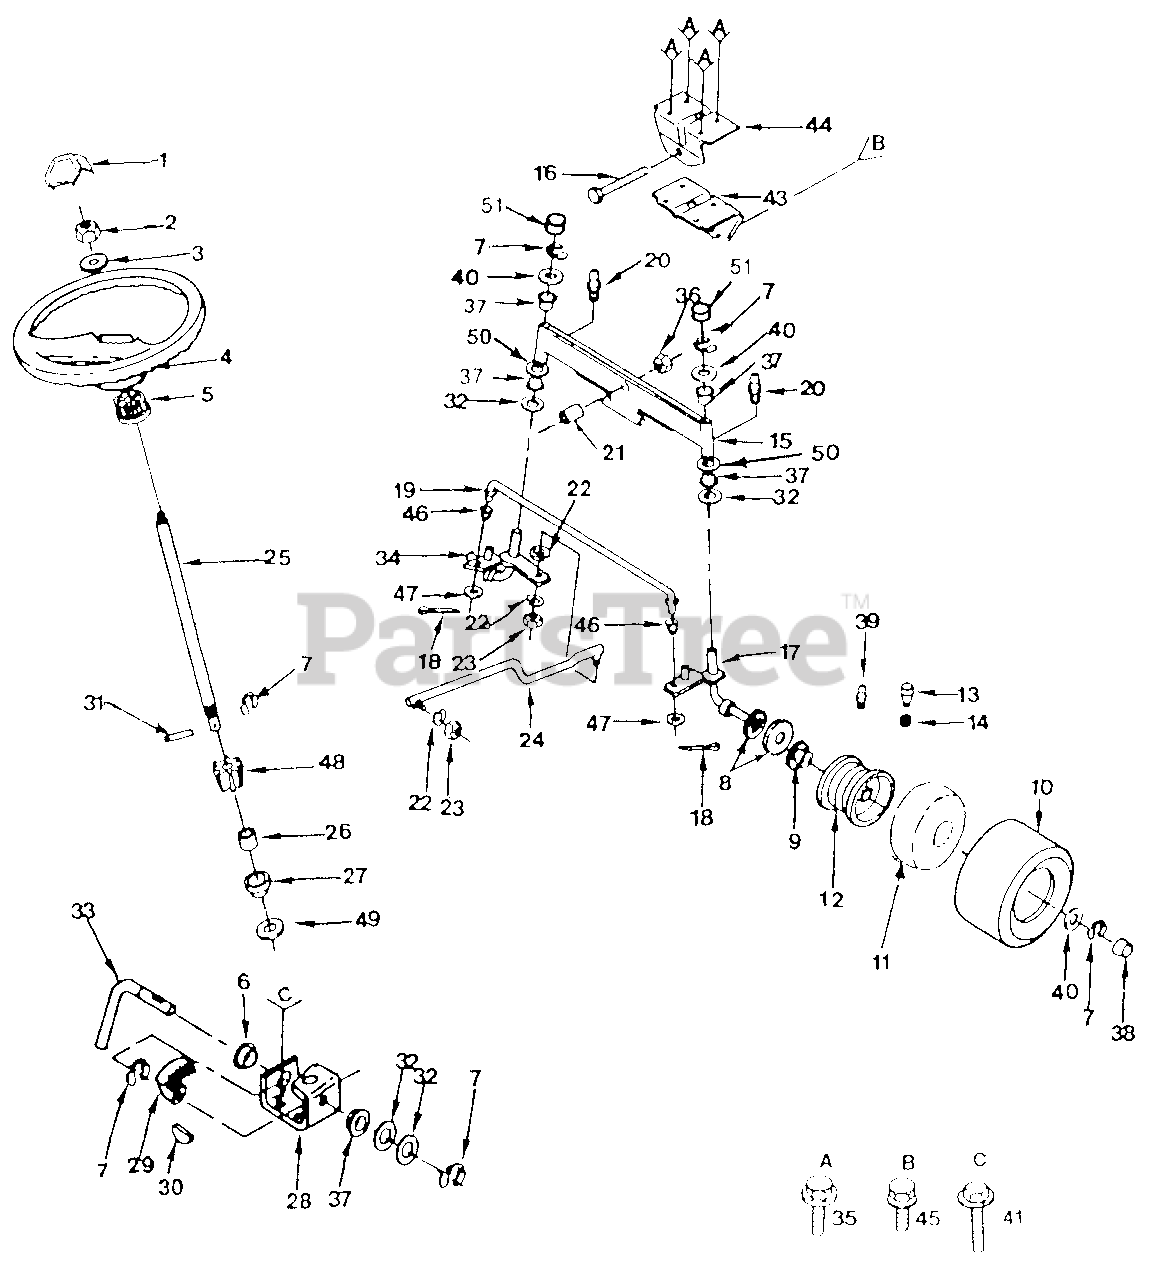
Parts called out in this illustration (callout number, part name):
1	Insert, Steering Wheel
2	Nut, Hex Jam Toplock 1/2-20
3	Washer 17/32 x 2-1/4 x .160
4	Steering Wheel
5	Adapter, Steering Wheel
6	Nyliner, Snap-in
8	Washer 25/32 x 1-1/4 x 16 Ga.
9	Bearings, Wheel, Front
10	Tire, 15 x 6.00-6 (Tubeless)
11	Tube, Tire
12	Rim Assembly - 6" Front
13	Stem, Valve
14	Cap, Valve
15	Axle Assembly, Front
16	Bolt, Hex 5/8-11 x 3-3/4
17	Spindle Assembly, R.H.
18	Pin, Cotter 1/8 x 3/4
19	Tie Rod
20	Fitting, Grease
21	Spacer Bearing, Front Axle
22	Lockwasher 3/8
23	Nut, Hex 3/8-24
25	Shaft, Steering
27	Bushing, Steering Rod
28	Bracket Assembly, Steering
29	Gear, Sector
30	Woodruff Key 3/16 x 3/4
31	Drive Pin 3/16 x 1
32	Bearing Thrust
33	Rod, Steering
34	Spindle Assembly, L.H.
35	Screw, Hex Washer Hd. Thread Forming Type TT 3/8-16 x 3/4
36	Nut, Flange 5/8-11
39	Grease Fitting
40	Washer 25/32 x 1-5/8 x 16 Ga.
41	Screw, Hex Washer Thrdl 3/8-16 x 3/4
43	Support, Saddle, Front
44	Support, Saddle, Rear
45	Screw, Hex Washer Thd. Rolling 5/16-18 x 1/2
46	Bushing
47	Washer 13/32 x 7/8 x 16 Ga.
48	Gear, Pinion
49	Washer, Hardened
50	Washer 27/32 x 1-1/4 x 16 Ga.
51	Spindle Cap
